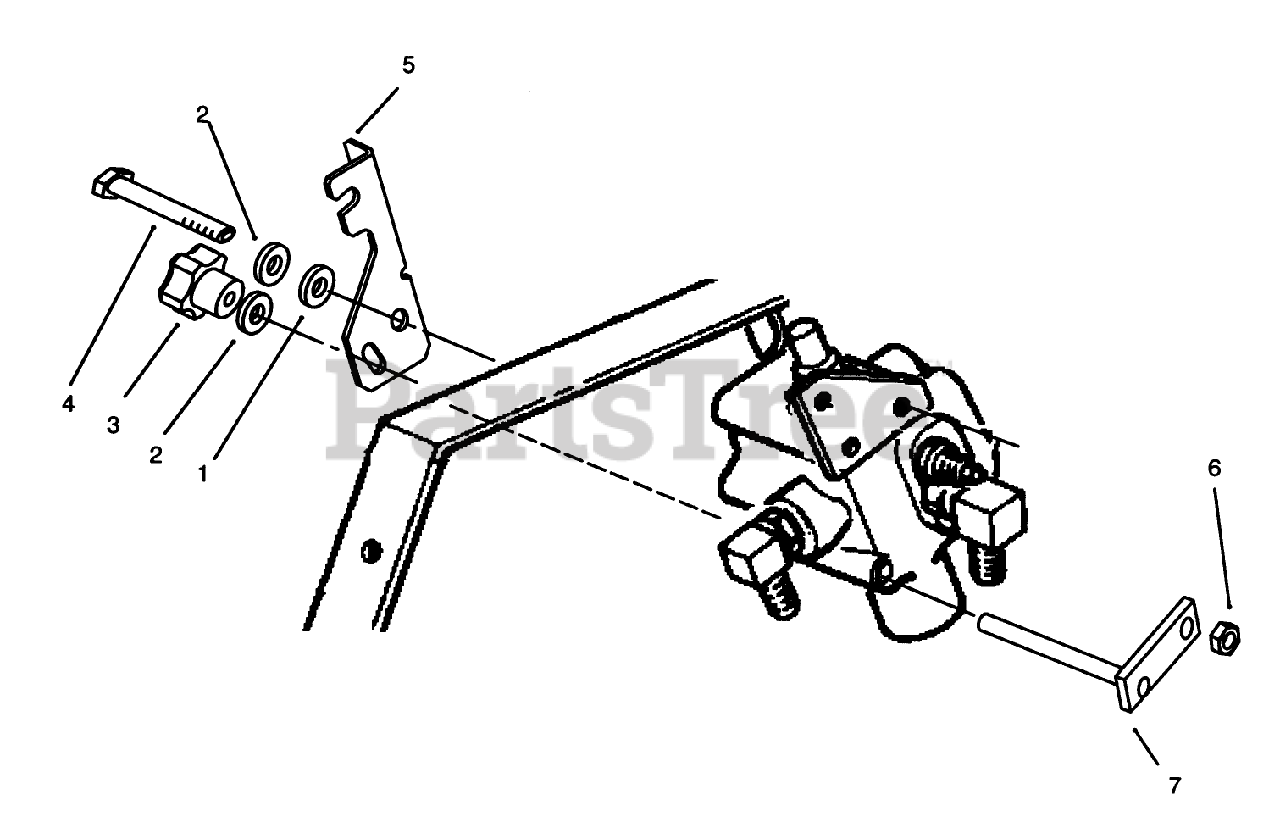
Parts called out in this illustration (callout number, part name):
1	SPACER - LATCH
2	WASHER-FLAT
3	KNOB-CHUTE
4	SCREW-HH
5	BRACKET - HYDRO LOCK
6	NUT-LOCK, NI
7	WA - CONTROL BLOCK
